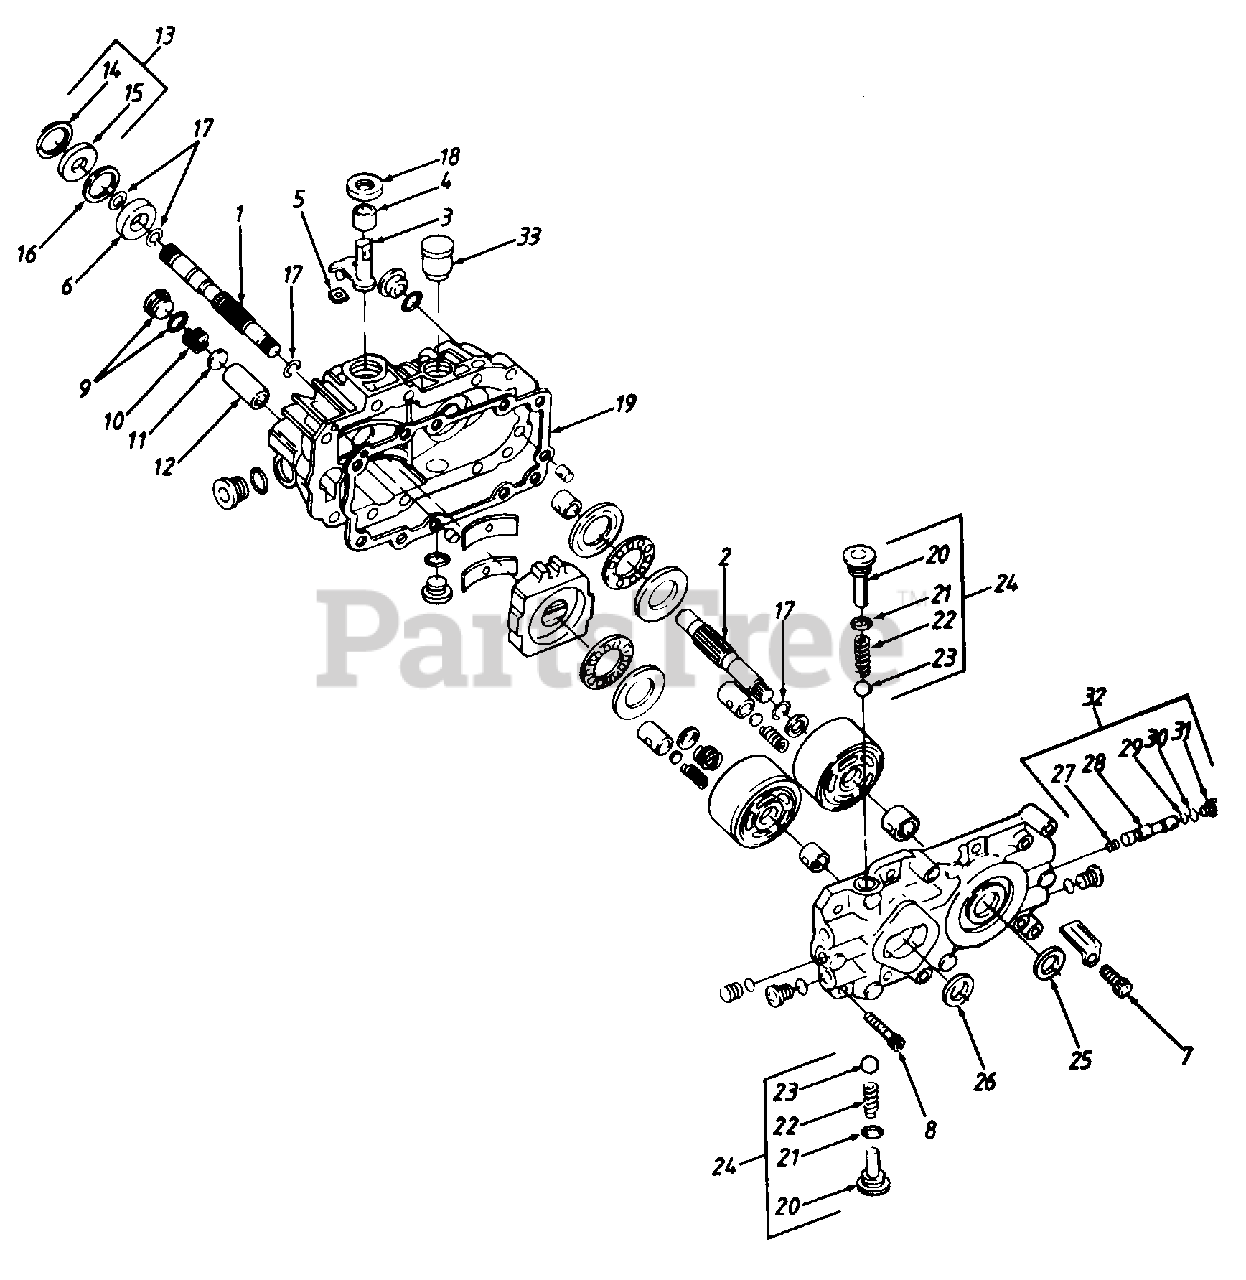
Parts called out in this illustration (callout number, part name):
1	Shaft-Pump
2	Shaft-Motor
3	Arm, Trunnion
4	Bearing, Journal
5	Guide, Slot
6	Bearing, Ball
7	Screw Socket Head
8	Screw Socket Head
9	Plug
10	Spring, Filter
11	Washer, Filter
12	Filter
13	Kit, Seal
14	Ring, Retaining
15	Seal, Lip
16	Spacer
17	Ring, Retaining
18	Seal, Lip
19	Gasket
21	O-Ring
22	Spring
24	Kit, Check Valve
25	Seal, Lip
26	Seal, Lip
27	Spring
28	Spool, Bypass
29	O-Ring
30	O-Ring
32	Kit, Bypass Valve
33	Reservoir
